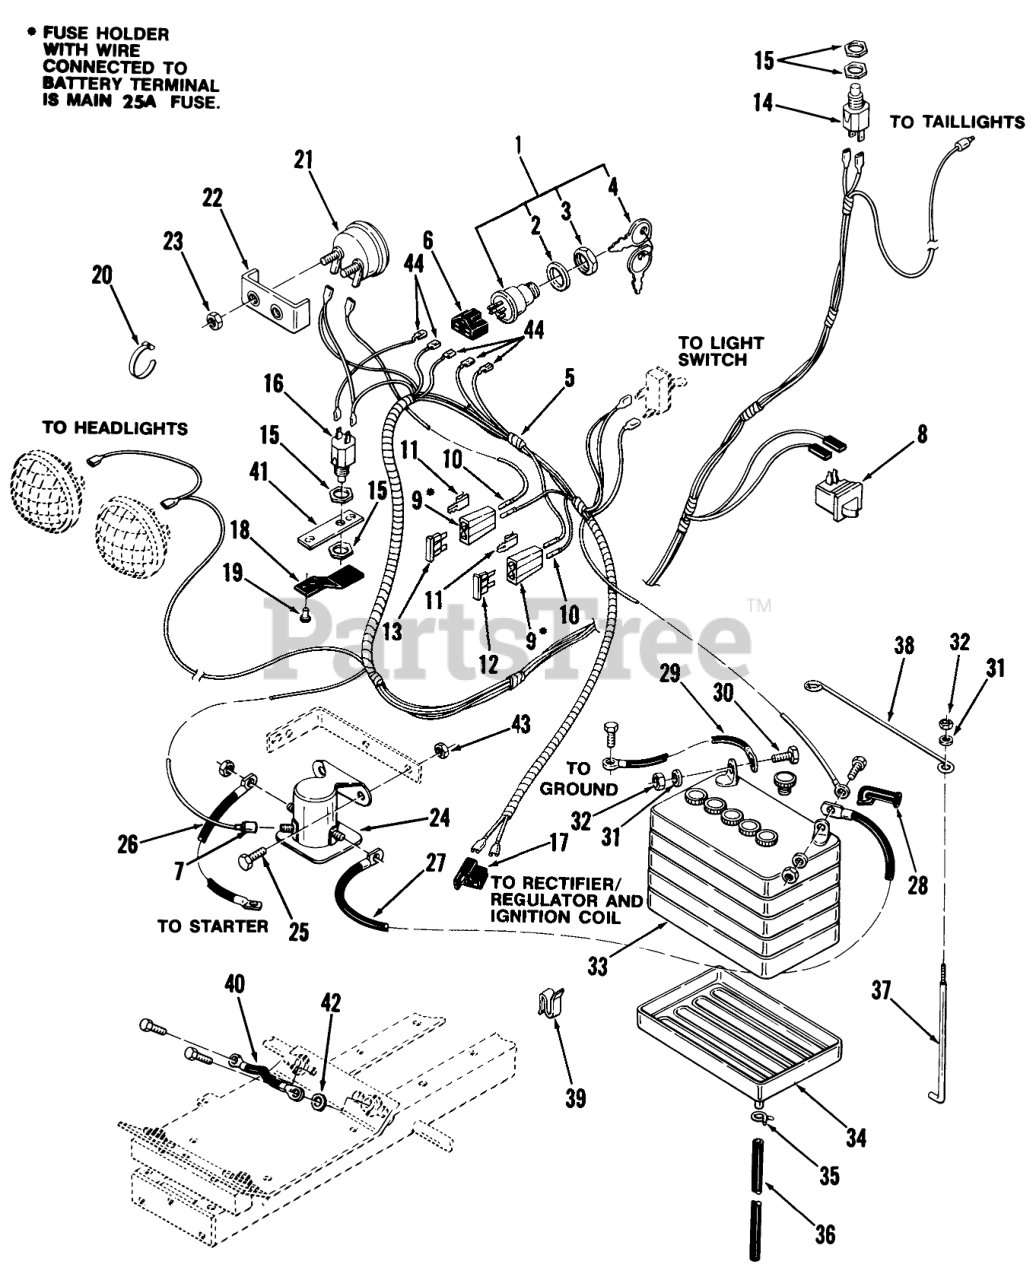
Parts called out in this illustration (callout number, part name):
1	SWITCH-IGNITION
2	LOCKWASHER
4	Key-EL
5	Wiring Harness
6	CONNECTOR-5 WAY-SERV
7	Terminal Part of 5
8	SWITCH INTERLOCK
9	AUTO-FUSEBLOCK TERM
10	TERMINAL-FUSE
12	FUSE-BLADE, 15 AMP
13	FUSE-BLADE, 25 AMP
14	SWITCH
15	NUT-HEX
16	SWITCH
17	CONNECTOR BODY
18	CLIP-SWITCH
19	RIVET
20	PLASTIC TIE
21	AMMETER W/CLAMP
22	Clamp
23	HEX NUT 10-32 E.S.
24	SOLENOID
25	Screw
26	Cable-Solenoid To Starter
27	Cable
28	Boot
29	Wire
30	Bolt
32	Nut
33	Battery
34	TRAY-BATTERY
35	Clamp
36	TUBE-BATTERY DRAIN
37	Hook
38	ROD-HOLD DOWN
39	CLIP
40	WIRE-GROUND
41	CLAMP-PTO SWITCH
42	LOCKWASHER
43	Nut
44	Terminal
